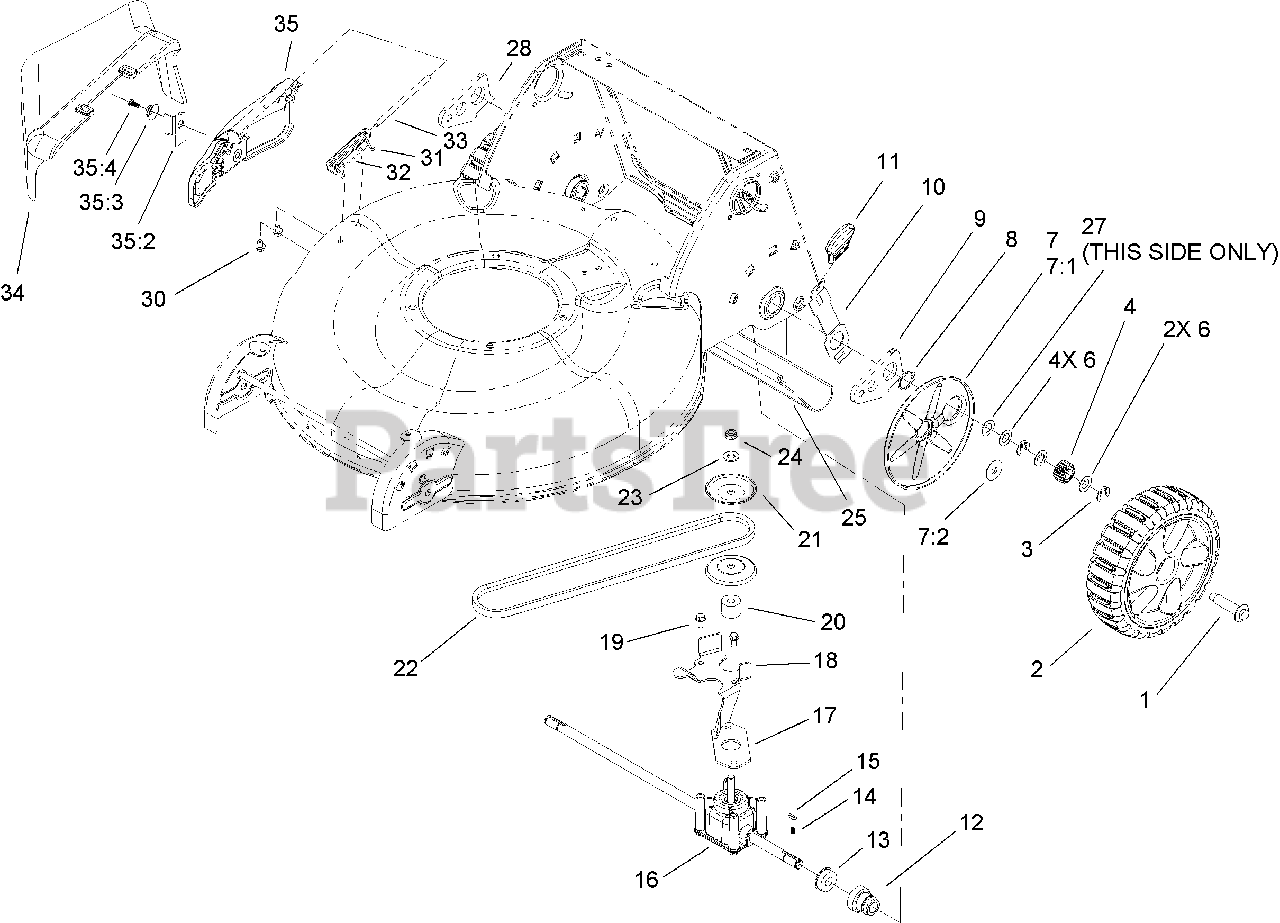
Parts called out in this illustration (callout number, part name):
1	BOLT-SHOULDER
2	REAR WHEEL ASM
3	KLIPRING-LOCKING
4	Gear-Pinion, 15t
6	Washer-Thrust
7	WHEEL COVER ASM
7:1	COVER-WHEEL
7:2	WASHER-STEPPED
8	RING-RETAINING
9	ARM-REAR PIVOT, LH
10	ARM-SPRING, REAR
11	KNOB-LEVER, HOC
12	RETAINER-BEARING, HOC
13	BEARING-BALL
14	SPRING-COMPRESSION
16	TRANSMISSION ASM
17	GASKET-GEARBOX
18	BRACKET-TRANSMISSION
19	SCREW-HWH
21	PULLEY-HALF
23	WASHER-FLAT
24	NUT-LOCK
25	SHIELD-TRAILING
28	ARM-REAR PIVOT, RH
30	SCREW-HWH
31	SPRING-TORSION
32	BRACKET-COVER
33	ROD-COVER
34	CHUTE-DISCHARGE, SIDE
35	DISCHARGE DOOR ASM
35:2	LATCH-DOOR
35:3	CAP-DOOR
35:4	SCREW-PLASTITE
